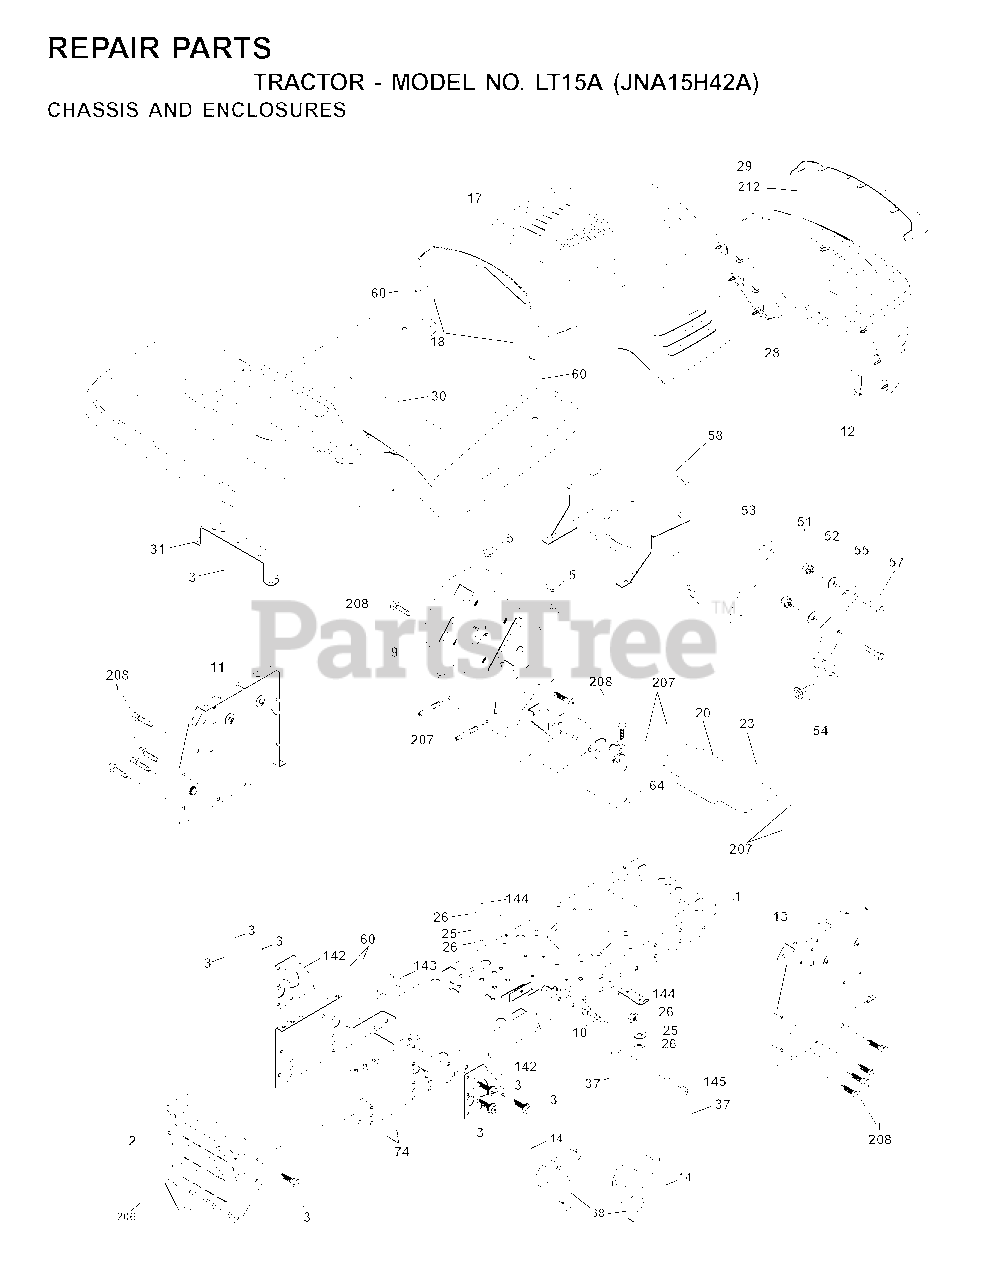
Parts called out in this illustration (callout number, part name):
1	CHASSIS STAMPING
2	DRAWBAR, 12GA
3	SCREW 3/8-16X3/4
5	BUMPER.RUBBER.HOOD
10	BOLT D
11	PANEL DASH LH
13	DASH PANEL RH
18	BUMPER HOOD T
20	PLATE MTG
23	GROMMET T
25	WASHER
26	NUT
38	BRACKET.ASM.PIVOT.MOWER.REAR
51	LOCKNUT
53	BRACKET.GRILLE.LH
57	BOLT
58	AIR DUCT P/L/LT
64	DASH LOWER
74	LOCKNUT
142	PLATE
143	BRACKET, SWAY BAR
144	BRACKET FOOTREST
145	ROD PIVOT CHASSIS/HOOD
206	SHOULDER BOLT 5/16-18TT
207	SCREW, 5/16-18 X 1/2
208	SCREW 3/8-16X1/2
